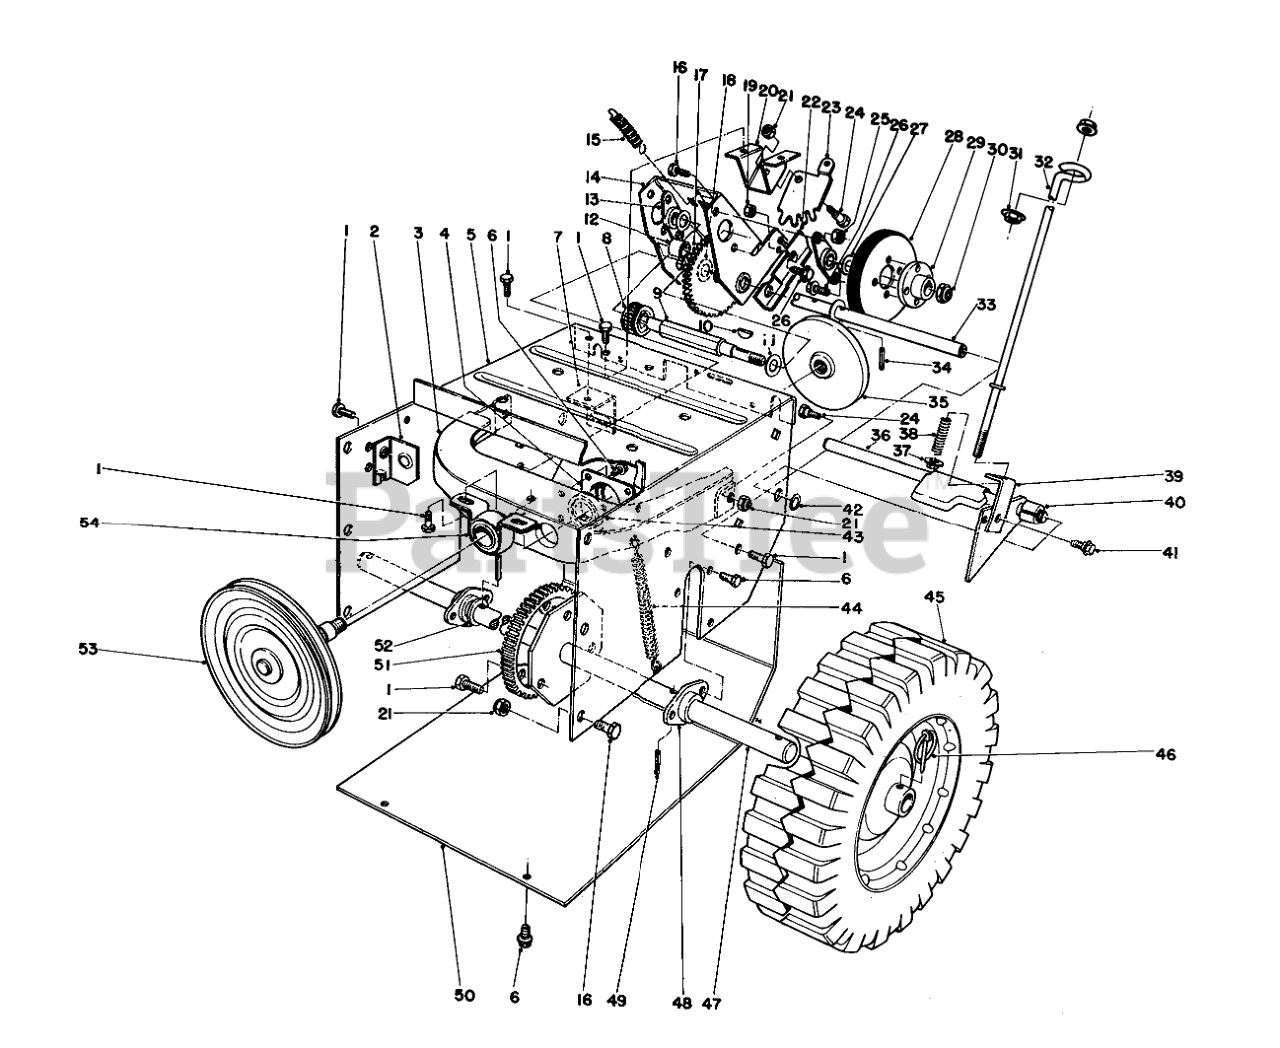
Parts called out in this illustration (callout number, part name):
1	SCREW-HWHTF
2	AUGER CLUTCH MTG FRT
3	"OBS" FRICTION PLT FRAME
4	CUP-BEARING
5	Frame-Traction
6	SCREW
7	BRACKET-MOUNT, REAR
8	PINION
9	SHAFT-WHEEL, FRICTION
10	KEY-WOODRUFF
11	WASHER-FLAT
12	5/8ID X 1LG BUSHING
13	BEARING-WHEEL, FRICTION
14	BRACKET-SLIDING
15	SPRING-TRACTION
16	SCREW-HH
17	Intermediate Gear & Bushing (Incl. Ref. #12)
18	WASHER-SPECIAL
19	NUT-LOCK, NI
20	MOUNT-LEVER
21	NUT-LOCK, NI
22	CAM-RECEIVER
23	GEAR-QUADRANT
24	BOLT-SHOULDER
25	NUT-LOCK, CONE
26	Screw
27	WASHER-THRUST
28	WHEEL-FRICTION
29	HUB-WHEEL, FRICTION
30	NUT-LOCK, NI
31	NUT-HF
32	ROD-TRACTION, LOWER
33	SHAFT-PIVOT
34	PIN-SPRING
35	PLATE-FRICTION
36	Traction Engagement Asm.
37	NUT-LOCK, HHF
38	SPRING
39	BRACKET-TRACTION
40	SPACER
41	SCREW
42	RING-RETAINING
43	BEARING-BALL
44	SPRING-PLATE, FRICTION
45	Wheel
46	PIN-LYNCH
47	AXLE SHAFT WA
48	BEARING-AXLE
49	PIN-SPRING
50	Bottom Cover
51	GEAR-AXLE
52	WASHER-THRUST
53	Pulley & Shaft
54	BUSHING ASM
